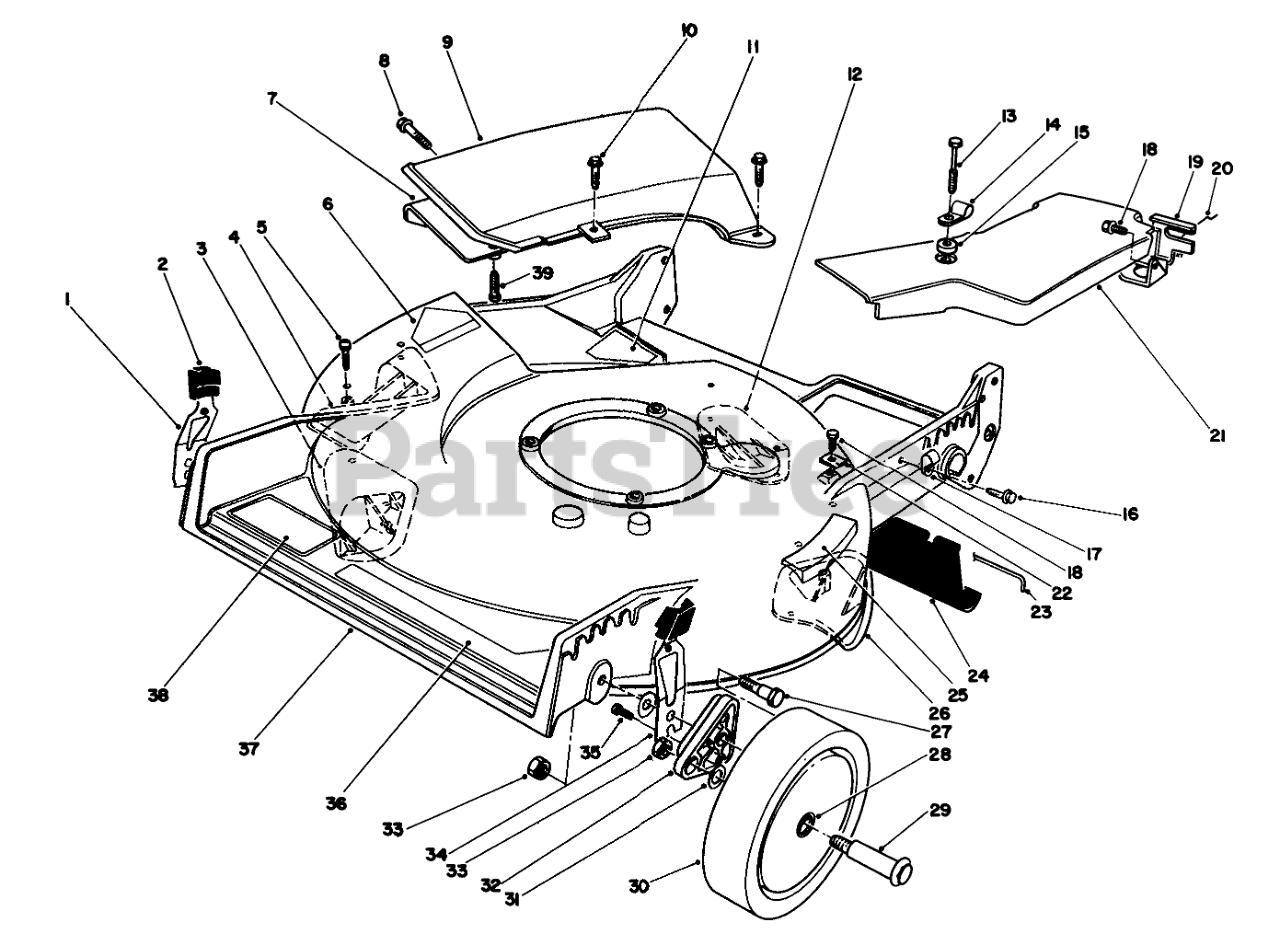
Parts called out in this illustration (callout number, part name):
1	RH SPRING ARM ASSEMBLY
2	KNOB-ARM
3	KICKER
4	KICKER
5	SCREW-PPH
6	DECAL-DANGER
7	Deflector-Recycler
8	SCREW AND WASHER ASM
9	Recycler Cover Assembly (Incl. Ref. #7 & 39)
10	SCREW-HWH
11	DECAL - DANGER
12	KICKER
13	SCREW-SPECIAL
14	CLAMP-CABLE
15	WASHER
16	SCREW
17	CLAMP-CABLE
18	SCREW-HWHTF
19	Bracket-Adj. Trac
20	RETAINER-CABLE
21	BELT COVER
22	CLAMP-CABLE
23	ROD-SHIELD
24	SHIELD-TRAILING
25	STEP PAD DECAL
26	KICKER
27	SCREW-SHOULDER
28	BUSHING
29	WHEEL BOLT
30	Wheel & Tire Assembly (Incl Ref. #28)
31	WASHER
32	ARM-PIVOT, FRONT
33	Nut
34	LH SPRING ARM ASSEMBLY
35	SCREW-HWH
36	DECAL - DECK
37	Housing (Incl. Ref. #3-6, 12, 18 & 26)
38	DECAL
39	Screw-Plastite
